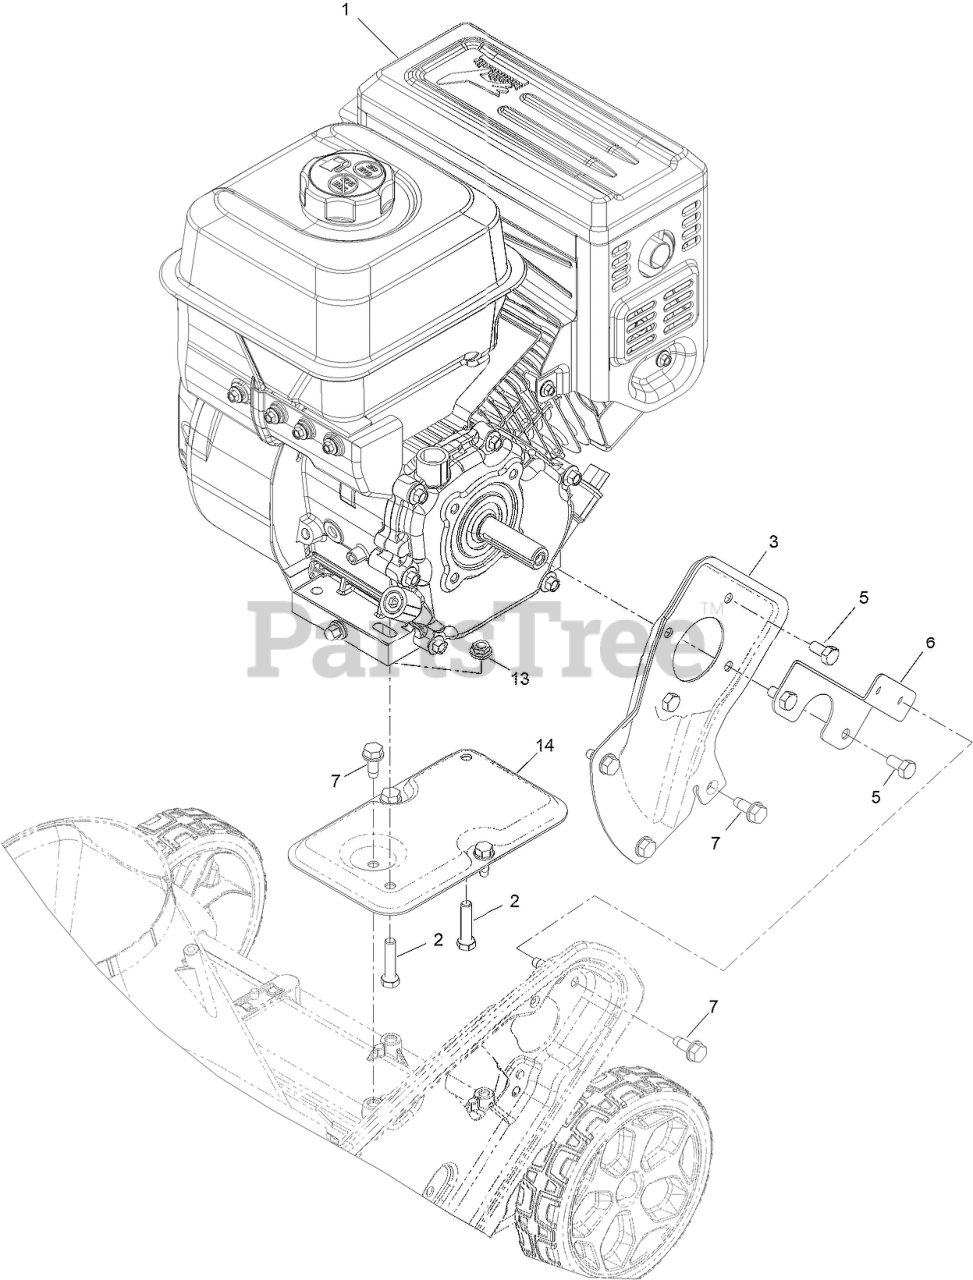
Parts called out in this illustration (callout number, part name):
1	ENGINE - G210FS-4
2	SCREW-HH
3	PLATE-ENGINE, PTO
5	BOLT
6	SUPPORT-ENGINE, SIDE
7	SCREW-THD ROLL, HWH
13	NUT-HF
14	SUPPORT-ENGINE
